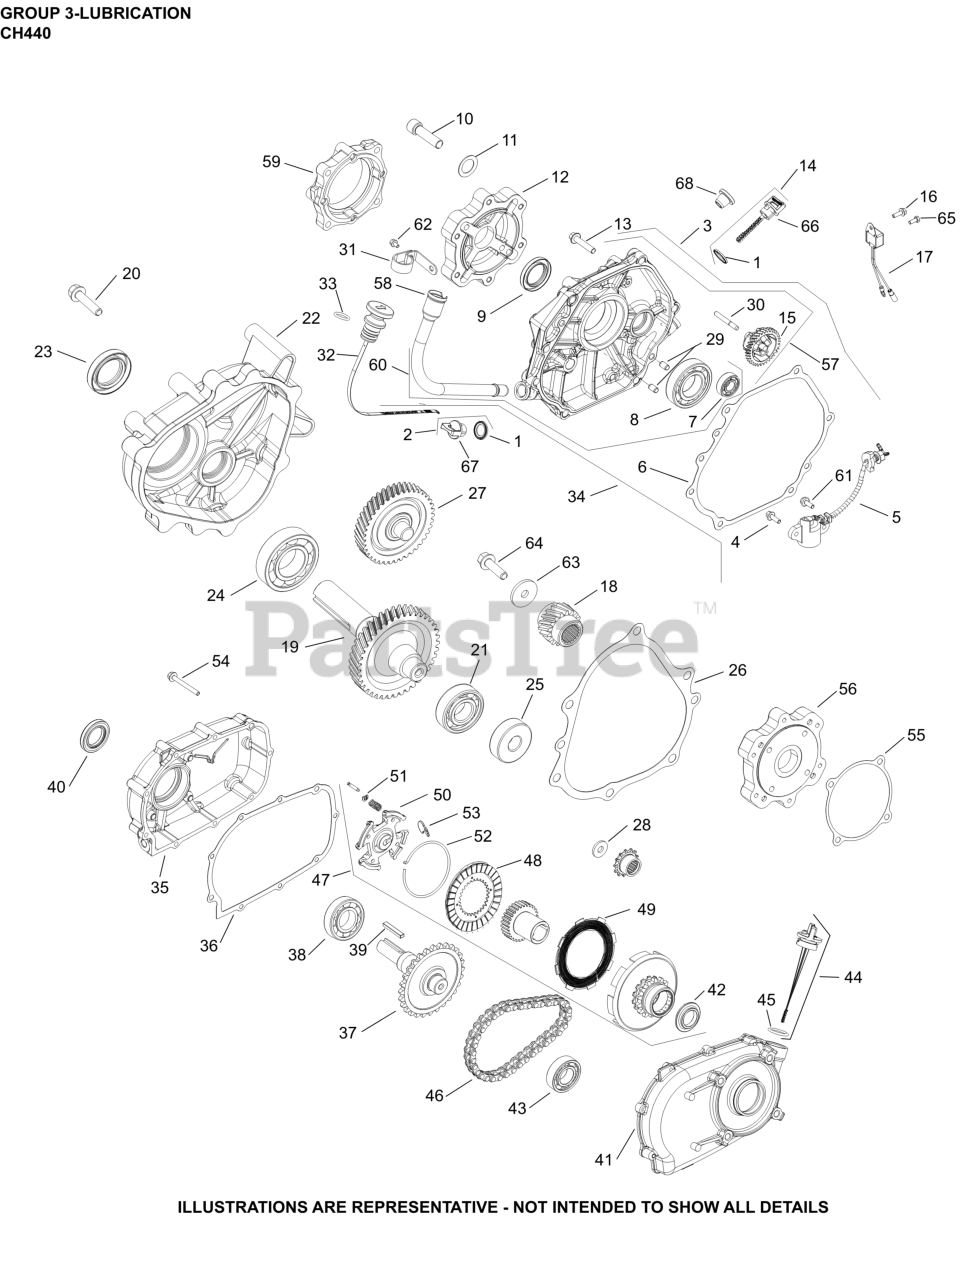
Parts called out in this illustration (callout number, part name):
1	SEAL, DIPSTICK
3	KIT, CLOSURE PLATE ASSEMBLY
4	SCREW, M6 X18
5	SWITCH, OIL SENSOR ASSEMBLY
6	GASKET, CLOSURE PLATE
8	BEARING, BALL
13	SCREW, CLOSURE PLATE
14	DIPSTICK ASSEMBLY
15	GOVERNOR ASSEMBLY
16	SCREW, HEX/PHILLIPS M5
17	CONTROL, OIL ALERT UNIT
20	SCREW, M8 X 35
23	SEAL, RADIAL SHAFT
29	PIN, DOWEL (8MM)
30	SHAFT, GOVERNOR GEAR
35	REDUCTION COVER
36	GASKET, REDUCTION CASE
37	SHAFT, PTO ASSEMBLY
38	BEARING, CRANKSHAFT
39	FLAT KEY 7 X 5 X 40
40	SEAL, OIL
41	REDUCTION CASE
42	WASHER, THRUST
43	BEARING, BALL
44	DIPSTICK ASSEMBLY
45	O-RING, DIPSTICK
47	CLUTCH ASSEMBLY
48	FRICTION DISC
49	CLUTCH PLATE
50	WEIGHT HOLDER
51	RETAINER, RING
52	WEIGHT RETAINER
53	WEIGHT, CLUTCH
57	PLATE, CLOSURE & BEARING
61	SCREW, M6 X 16
66	DIPSTICK - USE 17 038 08-S
